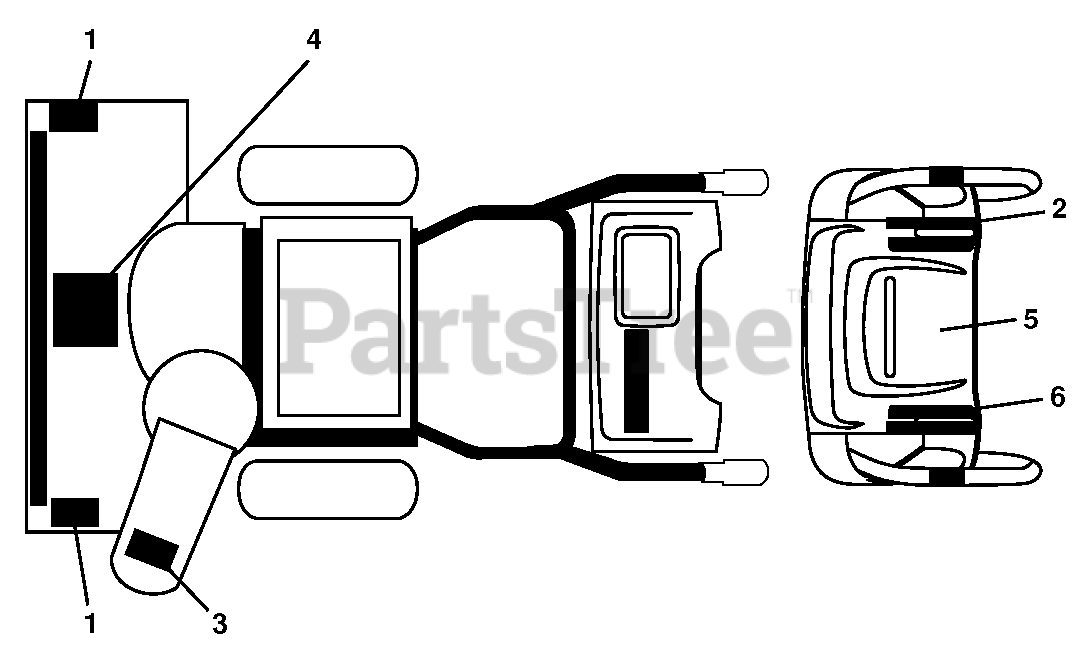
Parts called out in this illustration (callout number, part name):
1	DECAL.SNOWTHR.AUGER
2	DECAL.CONS.RT.SPD/LEV/PWRST.
3	DECAL.SNOWTHR.CHUTE.SAFETY
4	DECAL.SNOWTR.READ.OWN.MAN.E/F
5	DECAL.CONSOLE.SNOW.INST.ENG/FR
6	DECAL.CONS.LT.SPD/LEV/PWRST.
